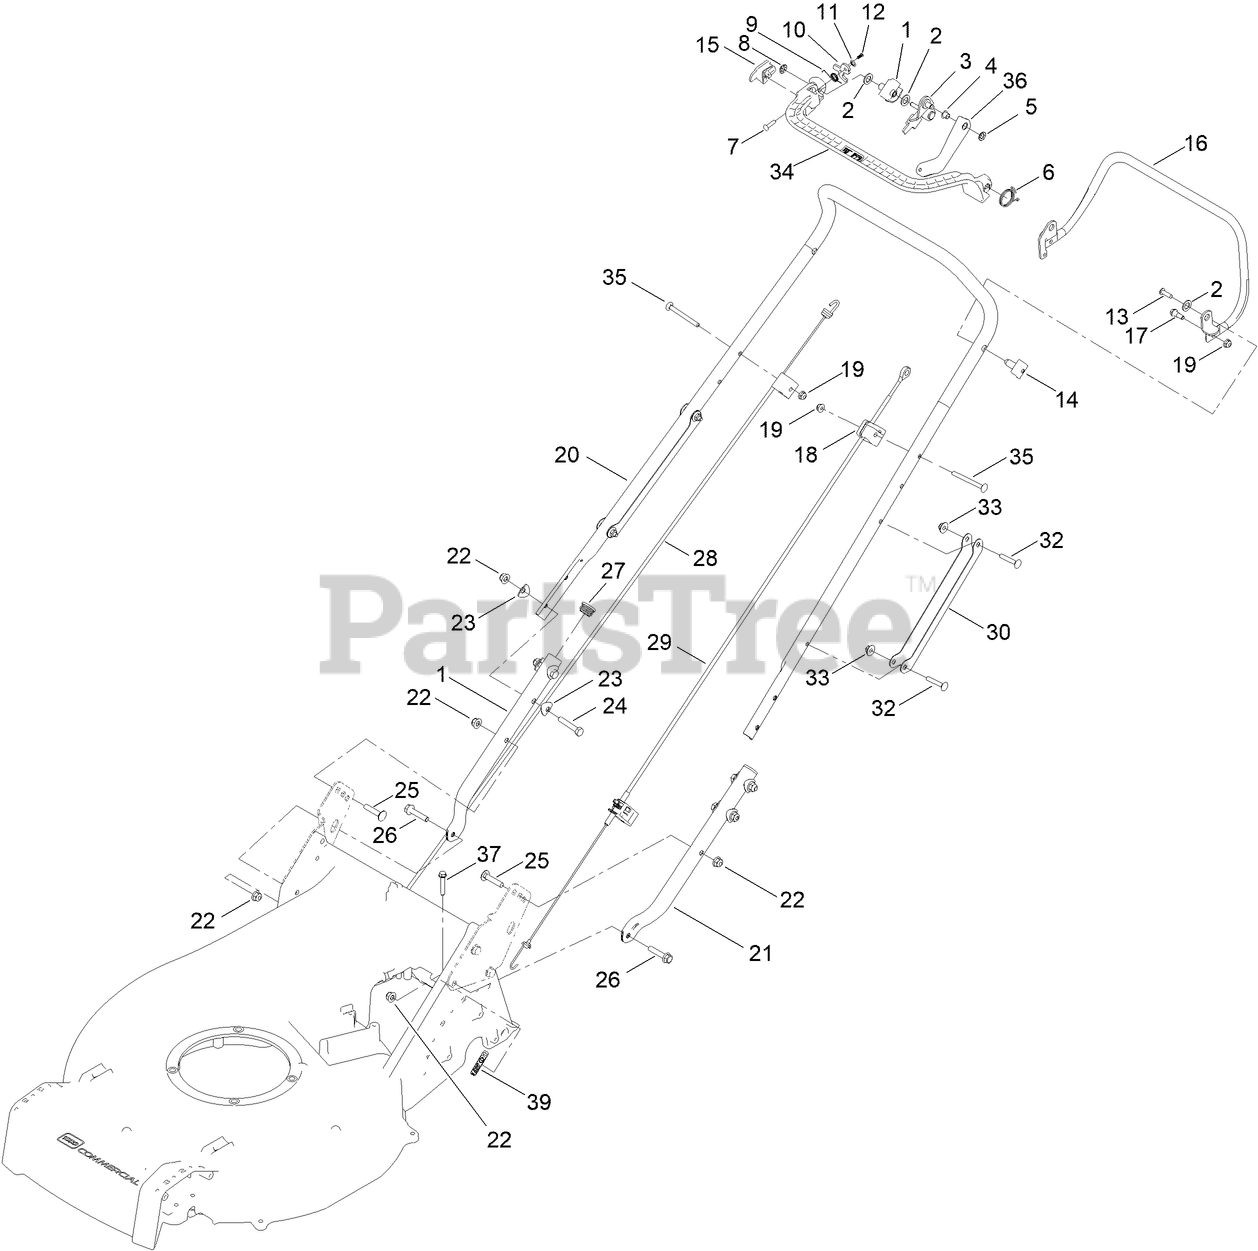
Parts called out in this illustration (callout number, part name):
1	CLAMP-BAR
2	WASHER-NYLON
3	ANCHOR PLATE WELDED
4	BUSH, IGUS (8 X 9 X 8)
5	WASHER-STARLOCK
6	LEVER-BAIL ARM, SPRING
7	LATCH-PIN
8	STARLOCK-DOMED
9	LEVER-BAIL, SPRING
10	LEVER-CATCH
11	FASTENER-STARLOCK, PUSH-ON
12	CLIP-TREE
13	SCREW
14	PIN-PIVOT
15	BUTTON-LATCH, BBC
16	LEVER-CLUTCH, GEARBOX
17	BOLT-SHOULDER
18	ANCHOR-CABLE
19	NUT-HF
20	HANDLE-UPPER
21	LOWER HANDLE
22	NUT-HF, NI
23	WASHER-CUP
24	SCREW-HH
25	BOLT-CARR
26	SCREW-HHF
27	PLUG-ROUND TUBE, 1 IN.
28	CABLE-BBC
29	CABLE-TRACTION, 60V
30	GUARD-CABLE, HANDLE
32	SCREW-CARR
33	NUT-HF
34	ARM-BAIL
35	SCREW-HANDLE
36	BBC LINKAGE ASSEMBLY
37	SCREW-HWH
